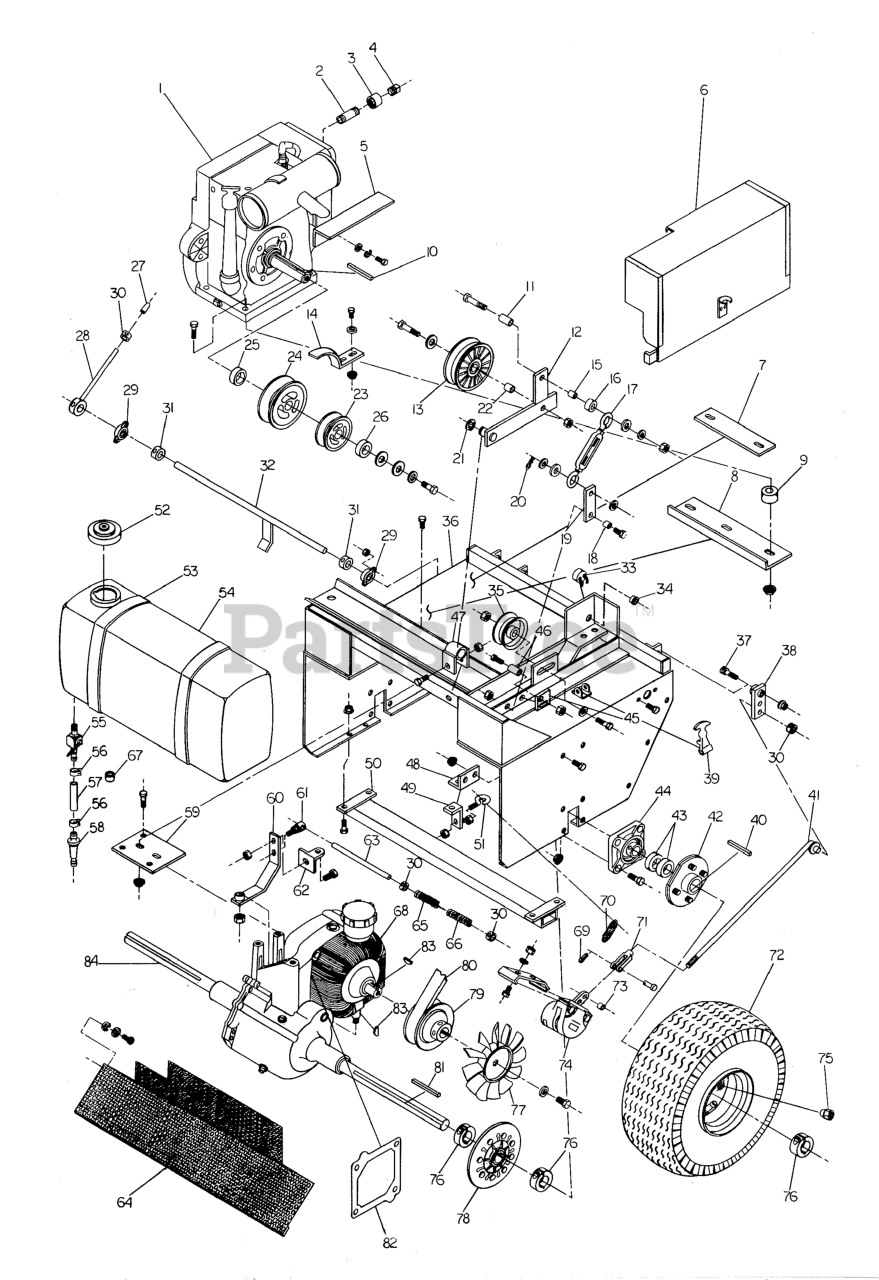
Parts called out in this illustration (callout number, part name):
2	Oil Drain Tube
3	COUPLER, 1/2" NPT
4	PLUG, 1/2" NPT
5	Side Guard Mount
6	Side Guard Weldment
7	Motor Deck Support Small
8	Motor Deck Support Long
9	SPACER, .39 x 1.75 x .88
10	KEY, 1/4 SQ. X 2-5/8
11	SPACER, .38 X .50 X 1.25, CZ
12	Bell Crank Weldment
13	PULLEY, Backside Idler
14	Engine Belt Guild
15	SPACER, .38 x .50 x .88
16	Delron Spacer
17	TURNBUCKLE ASSY
18	SPACER, .38 x .50 x .27
19	Linkage Arm
20	HAIRPIN CLIP
21	C-CLIP
22	SPACER, Shoulder
25	SPACER, 1.14 x 1.50 x .50
26	SPACER, 1.14 x 1.50 x .34
27	Plastic Boot
28	Neutral Lever Handle Weld
29	5/8" Triangle Bearing
30	COLLAR, 5/16" Set
31	COLLAR, 5/8" Set
32	Neutral Lever Weldment
33	Interlock Module
34	Snap Bushing
35	Idler Pulley
36	Engine Deck Assembly
37	SHOULDER BOLT, 3/8 x 1
38	Brake Linkage Weldment
39	RUBBER LATCH
40	KEY, 1/4 SQ. X 2-1/2
41	Lower Brake Linkage Weld
42	4-Bolt Hub
43	SPACER, 1.02 x 1.56 x .50
44	4-Bolt Flange Bearing
45	Bell Crank Stop
46	SLEEVE
47	Bell Crank Mount Weldment
48	Brake Mount
49	Brake Spring Bracket
50	Bottom Deck Support
51	EYE BOLT
52	Gas Cap
53	Gas Tank Strap
54	Gas Tank
55	Fuel Shut-Off Valve
56	CLAMP, Hose
57	1/4" Gas Line
58	FUEL FILTER
59	Differential Plate
60	Direction Lever
61	Rod End Connector
62	Cable Connecting Bracket
63	5/16" Rod
64	Expanded Metal Guard Weld
65	SPRING, Compression
66	SPRING, Compression
67	Differential Mount Spacer
68	Hydrostatic Transmission
69	HAIRPIN CLIP
70	Draw Bar Spring
71	CLEVIS, 5/16-24, Steel
72	Drive Tire Assembly (Tire & Rim)
72	Tire Assembly 61" Deck
73	SPACER, .25 x .37 x .25
74	BRAKE CALIPER ASSEMBLY, LH, Complete
74	BRAKE CALIPER ASSEMBLY, RH, Complete
75	LUG NUT, 1/2-20
76	COLLAR, 1" Split
78	Brake Disc
81	KEY, 1/4 SQ. X 1
83	KEY, #3 Woodruff
84	Differential 48" Deck
84	Differential 61" Deck
